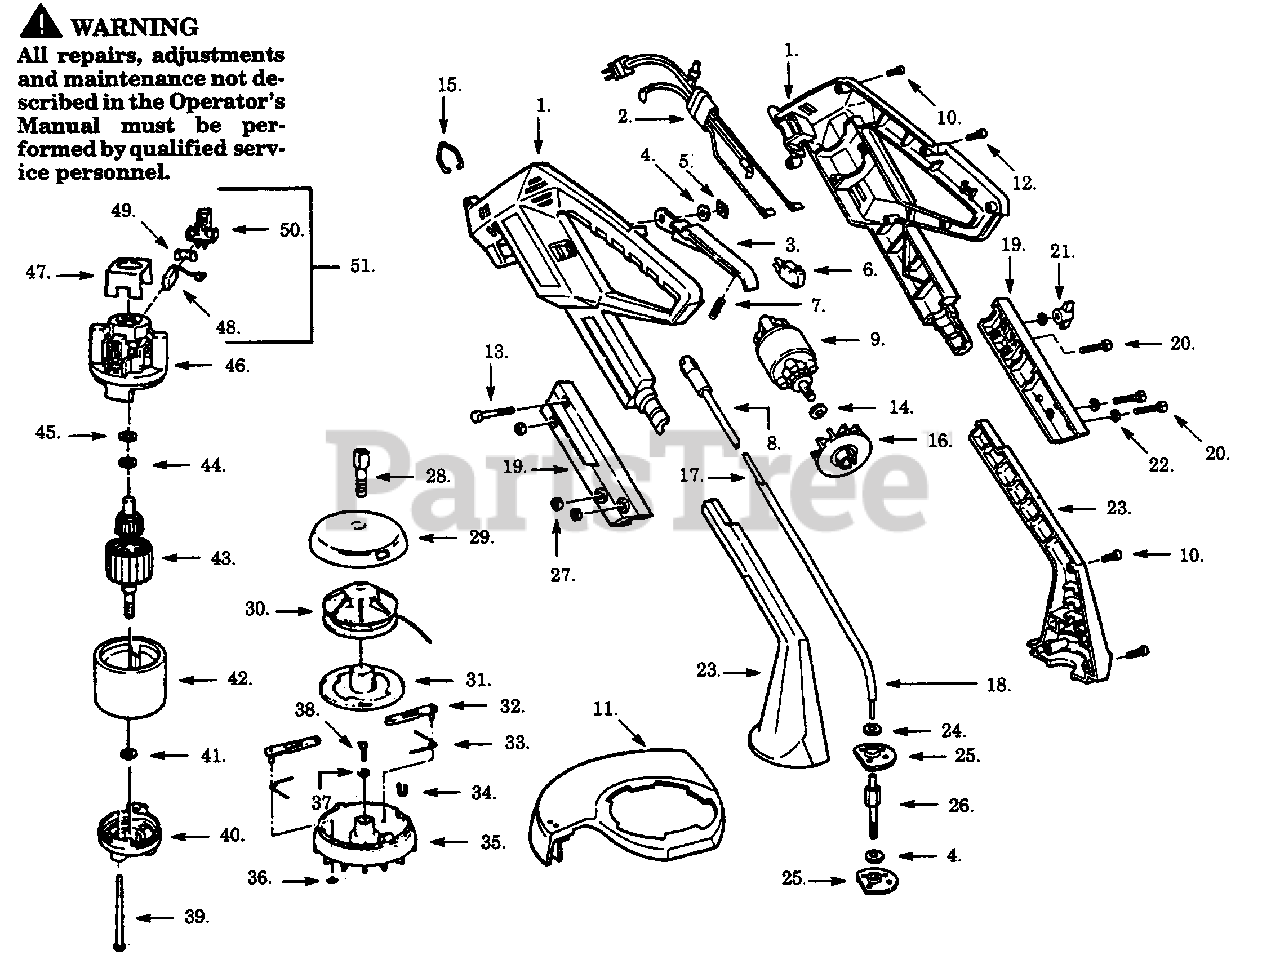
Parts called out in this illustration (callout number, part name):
1	Motor Hsg. Set
2	Harness Ass'y.
4	Washer, (As required)
5	Push Nut
7	Trigger Spring
8	Upper Sleeve
9	Motor Ass'y.
11	Guard Ass'y.
17	Flex Shaft Ass'y.
19	Housing Set
23	Spindle Housing Set
24	Felt Washer
25	Bearing Holder
26	Shaft Adapter
28	Shaft Adapter
30	Spool w/Line
34	Line Saver
40	Endbell Ass'y. (Drive)
42	Field Ass'y.
43	Armature Ass'y.
44	Washer (As required)
46	Endbell Ass'y. (Brush)
47	Insulator
49	Brush Spring
50	Brush Holder
51	Brush Kit (Incl. 48,49,50)
